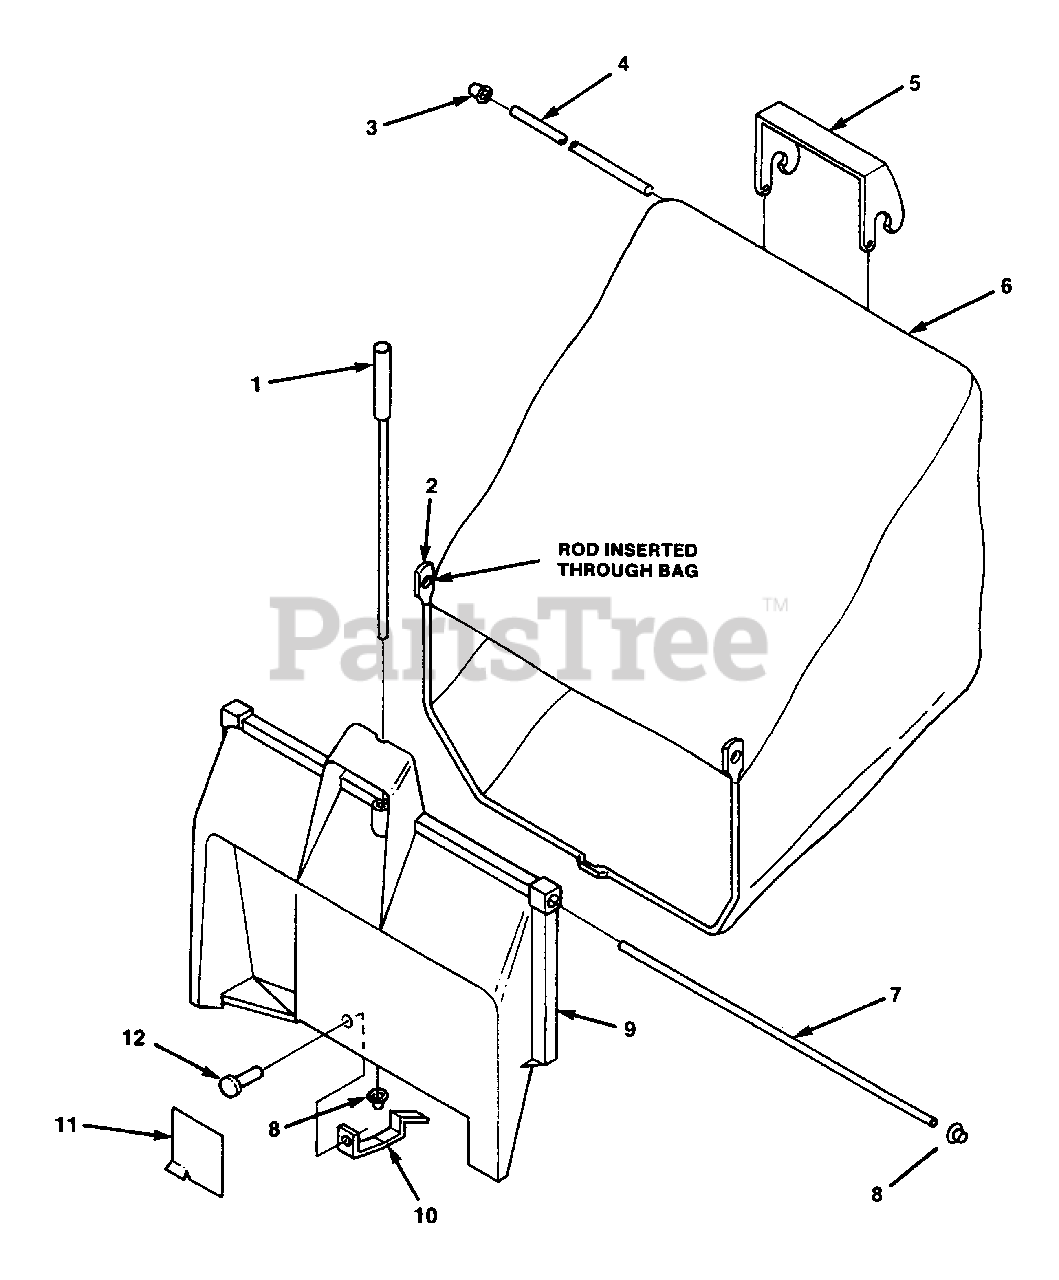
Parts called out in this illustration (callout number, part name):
1	LATCH, Rod
2	ROD, Bag Support
3	RETAINER
4	ROD, Upper Bag
6	BAG, Grass (Incl. Ref. No. 3, Qty. 1; Ref. No. 8, Qty. 1)
7	ROD, Bag Hinge
9	ADAPTOR, Bag
11	DEFLECTOR
